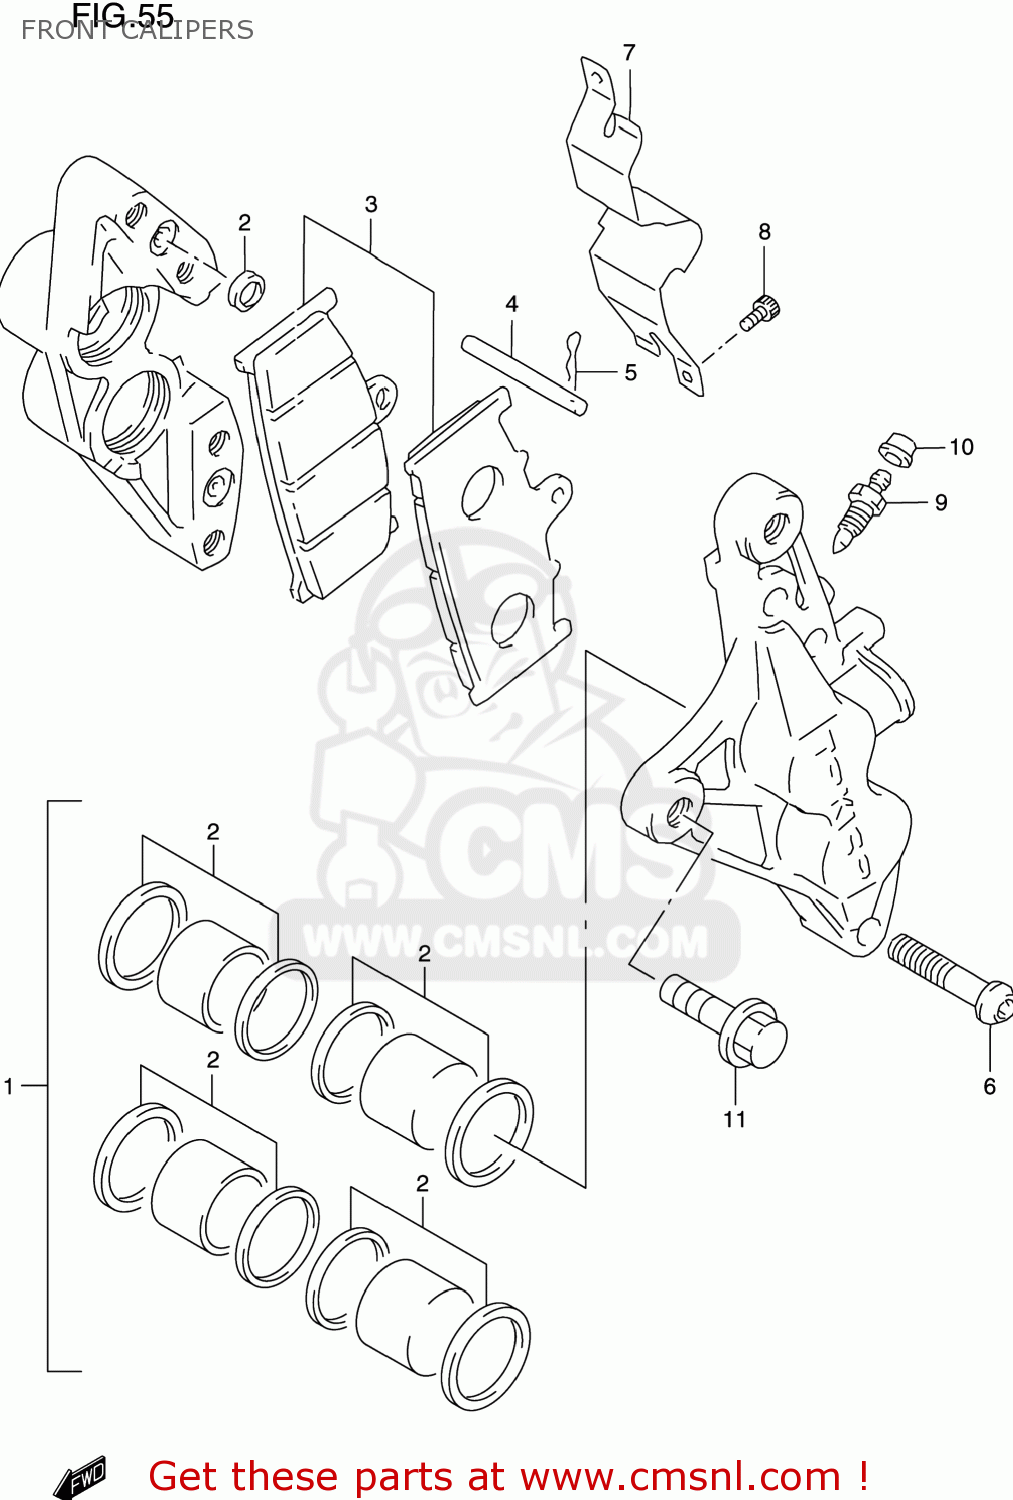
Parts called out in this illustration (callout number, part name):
1	PISTON SET
2	SEAL SET,PISTON
3	PAD SET (NAS)
4	PIN,PAD
5	CLIP,PAD PIN
6	BOLT,HOUSING
7	COVER,CALIPER DUST,R
8	SCREW
9	BLEEDER
10	CAP,BLEEDER PLUG
11	BOLT(10X30)
